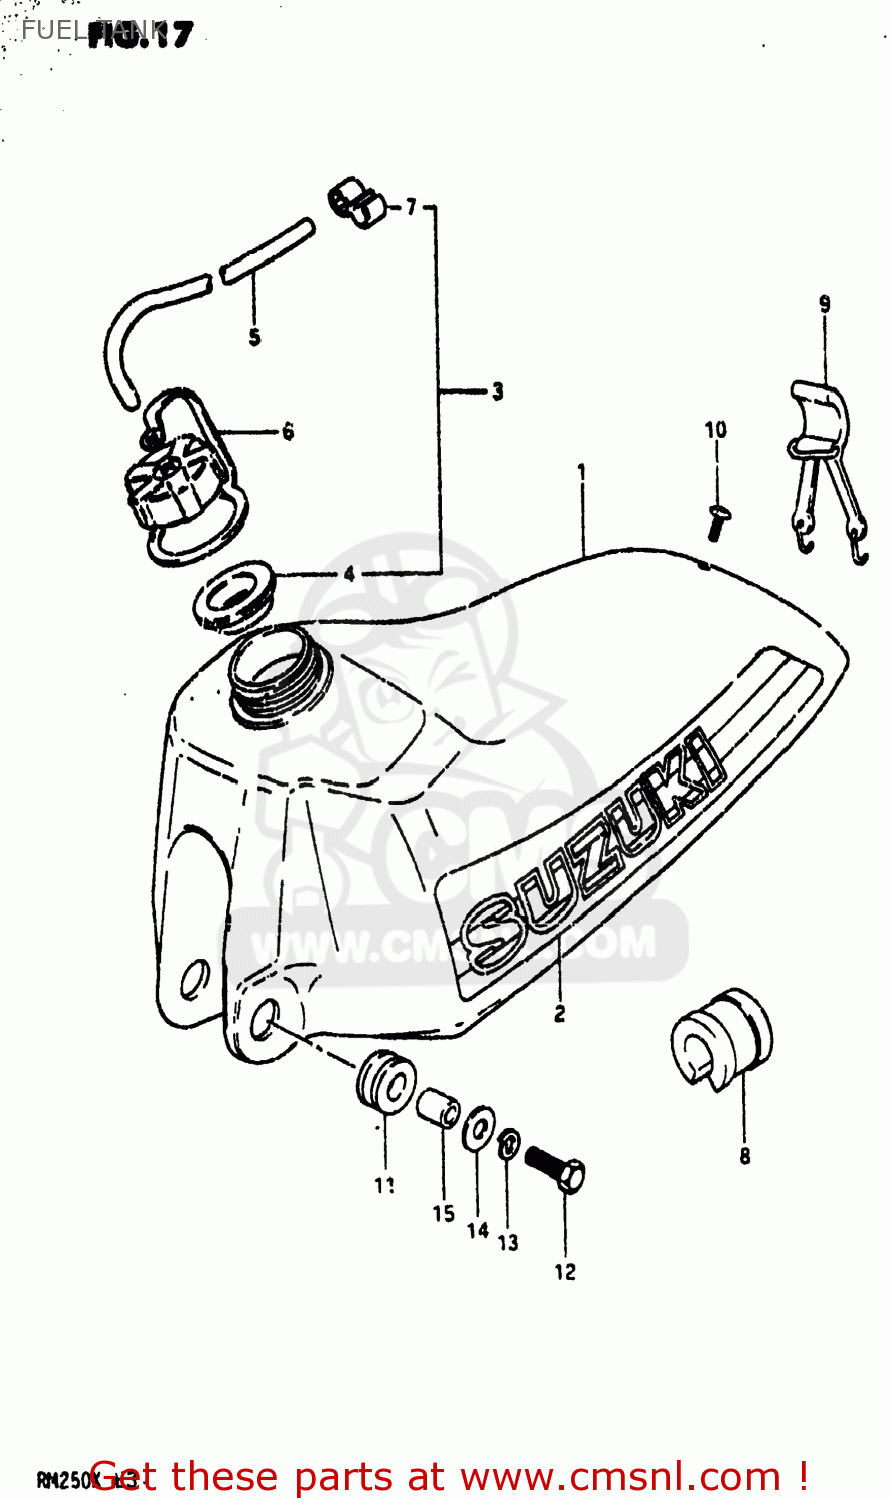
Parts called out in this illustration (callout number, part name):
1	TANK ASSEMBLY,FUEL
2	TAPE SET,FUEL TANK
3	CAP SET,FUEL TANK
4	GASKET,FUEL TANK CAP (NAS)
5	HOSE
6	BAND,FUEL TANK CAP
7	CLAMP,BREATHER HOSE
8	CUSHION,FUEL TANK UPR
9	BAND,FUEL TANK,REAR
10	SCREW (6X15)
11	CUSHION
12	BOLT (8X30)
13	LOCK WASHER
14	WASHER (8.5X29X1.6)
15	SPACER (8.8X12X15.5)
